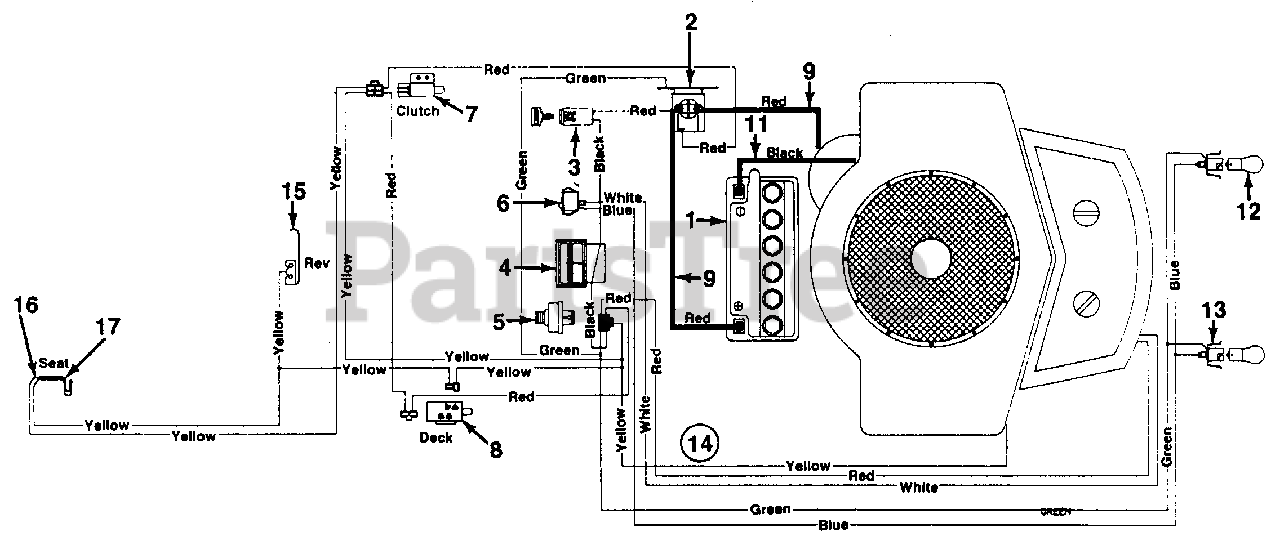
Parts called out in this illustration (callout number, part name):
1	Battery
2	Solenoid
3	Fuse 7.5 Amp
4	Ammeter
5	Ignition Switch
6	Light Switch
7	Safety Switch
8	Safety Switch
9	Electric Wire 14" Lg.
11	Ground Wire 7.5" Lg.
12	Lamp
13	Socket
14	Wire Harness
15	Spring Switch
16	Spring Switch
17	Spring Switch
